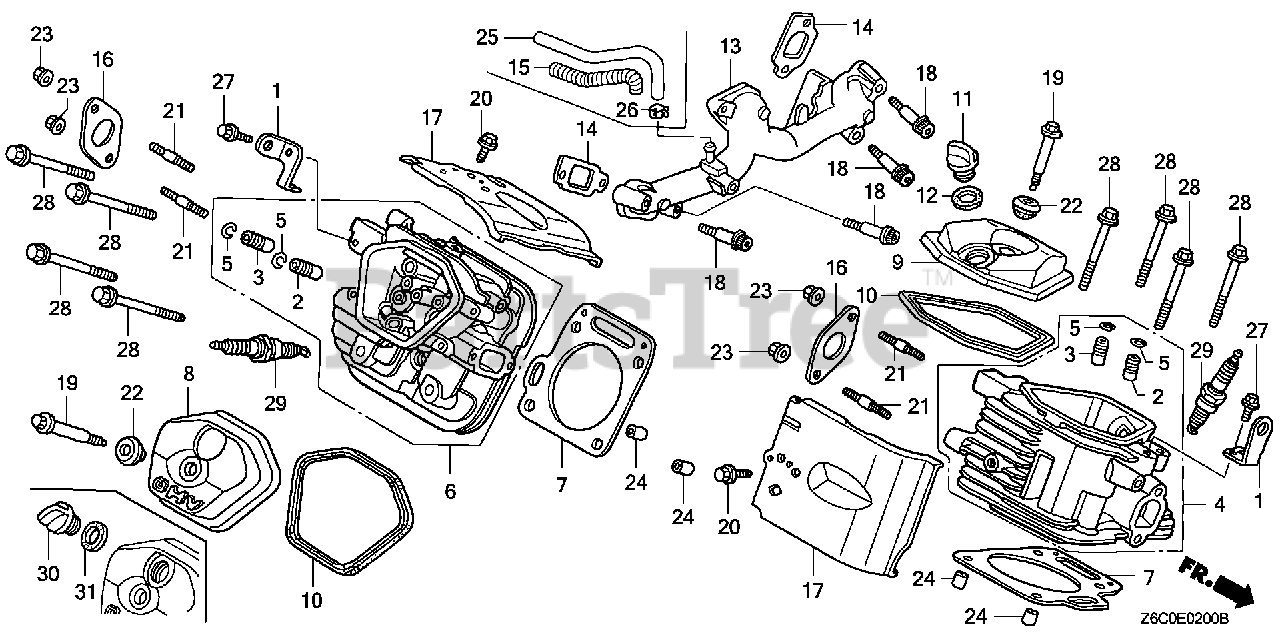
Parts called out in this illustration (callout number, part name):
1	HANGER, ENGINE
2	GUIDE, VALVE (OVER SIZE)
3	GUIDE, EX. VALVE (OVER SIZE)
4	CYLINDER HEAD (#1)
5	CLIP, VALVE GUIDE
6	CYLINDER HEAD (#2)
7	GASKET, CYLINDER HEAD
8	COVER, HEAD
9	COVER, HEAD FILLER
10	GASKET, HEAD COVER
11	CAP, OIL FILLER
12	GASKET, OIL FILLER CAP
13	MANIFOLD, IN.
14	GASKET, IN. MANIFOLD
16	GASKET, EX. PIPE
17	SHROUD, HEAD
18	BOLT, SOCKET (8X45)
19	BOLT, HEAD COVER
20	BOLT, FLANGE (6X14) (CT200)
21	BOLT, STUD (8X22)
22	WASHER, HEAD COVER
23	NUT, FLANGE (8MM)
24	PIN, DOWEL (12X20)
27	BOLT, FLANGE (8X20)
28	BOLT, FLANGE (10X80)
29	SPARK PLUG (BPR2ES) (NGK)
29	SPARK PLUG (J14CR-U) (DENSO)
29	SPARK PLUG (ZGR4A)
29	SPARK PLUG (J16CR-U) (DENSO)
29	SPARK PLUG (ZGR5A)
